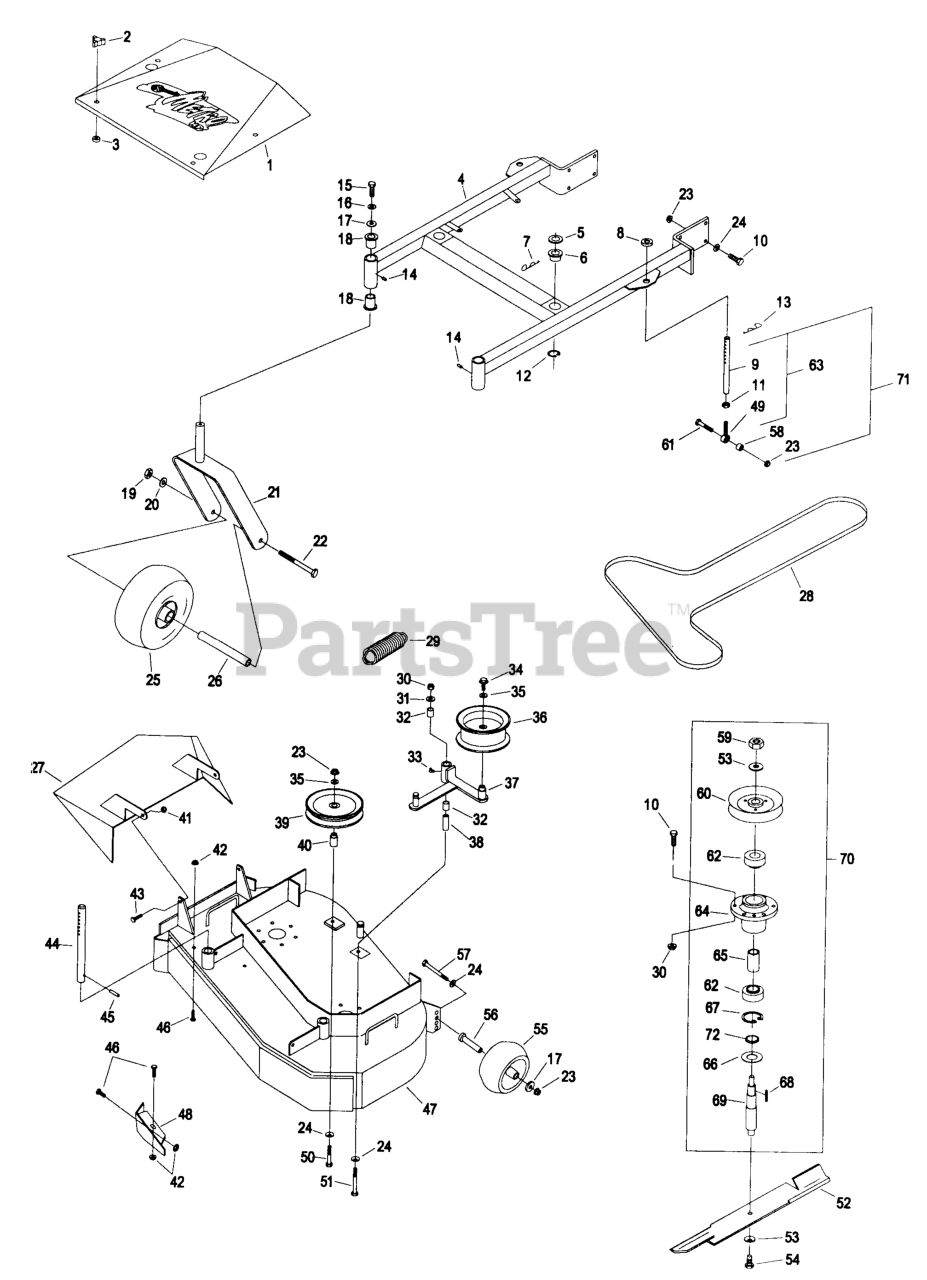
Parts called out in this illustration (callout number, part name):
1	SHIELD W/DECAL,MHP36
2	KNOB-3 PRONG
4	DECK SUPPORT W/BSHGS 36"
5	SPACER-DECK SUPPORT
6	BUSHING-DECK
9	LINK, DECK SUPPORT
13	PIN,HAIR COTTER
18	BEARING-FLANGED
28	BELT,DECK DRIVE
32	SLEEVE-BEARING
38	BUSHING-PIVOT, IDLER
39	PULLEY-IDLER
40	BUSHING-IDLER
44	ROD,DECK SUPPORT
47	ASM,DECK W/DECALS TTHP/MH
49	BALLJOINT
51	SCREW-HH
53	WASHER-SPRING
55	ROLLER-SCALP, ANTI
56	BUSHING-ROLLER
60	SHEAVE,W/HUB 5.72
62	BEARING
65	SPACER-BEARING
66	GUARD-BEARING, BOTTOM
68	KEY-RECTANGLE
69	SHAFT,SPINDLE
70	HOUSING,CUTTER COMPLETE
72	SPACER-PULLEY/BEARING
